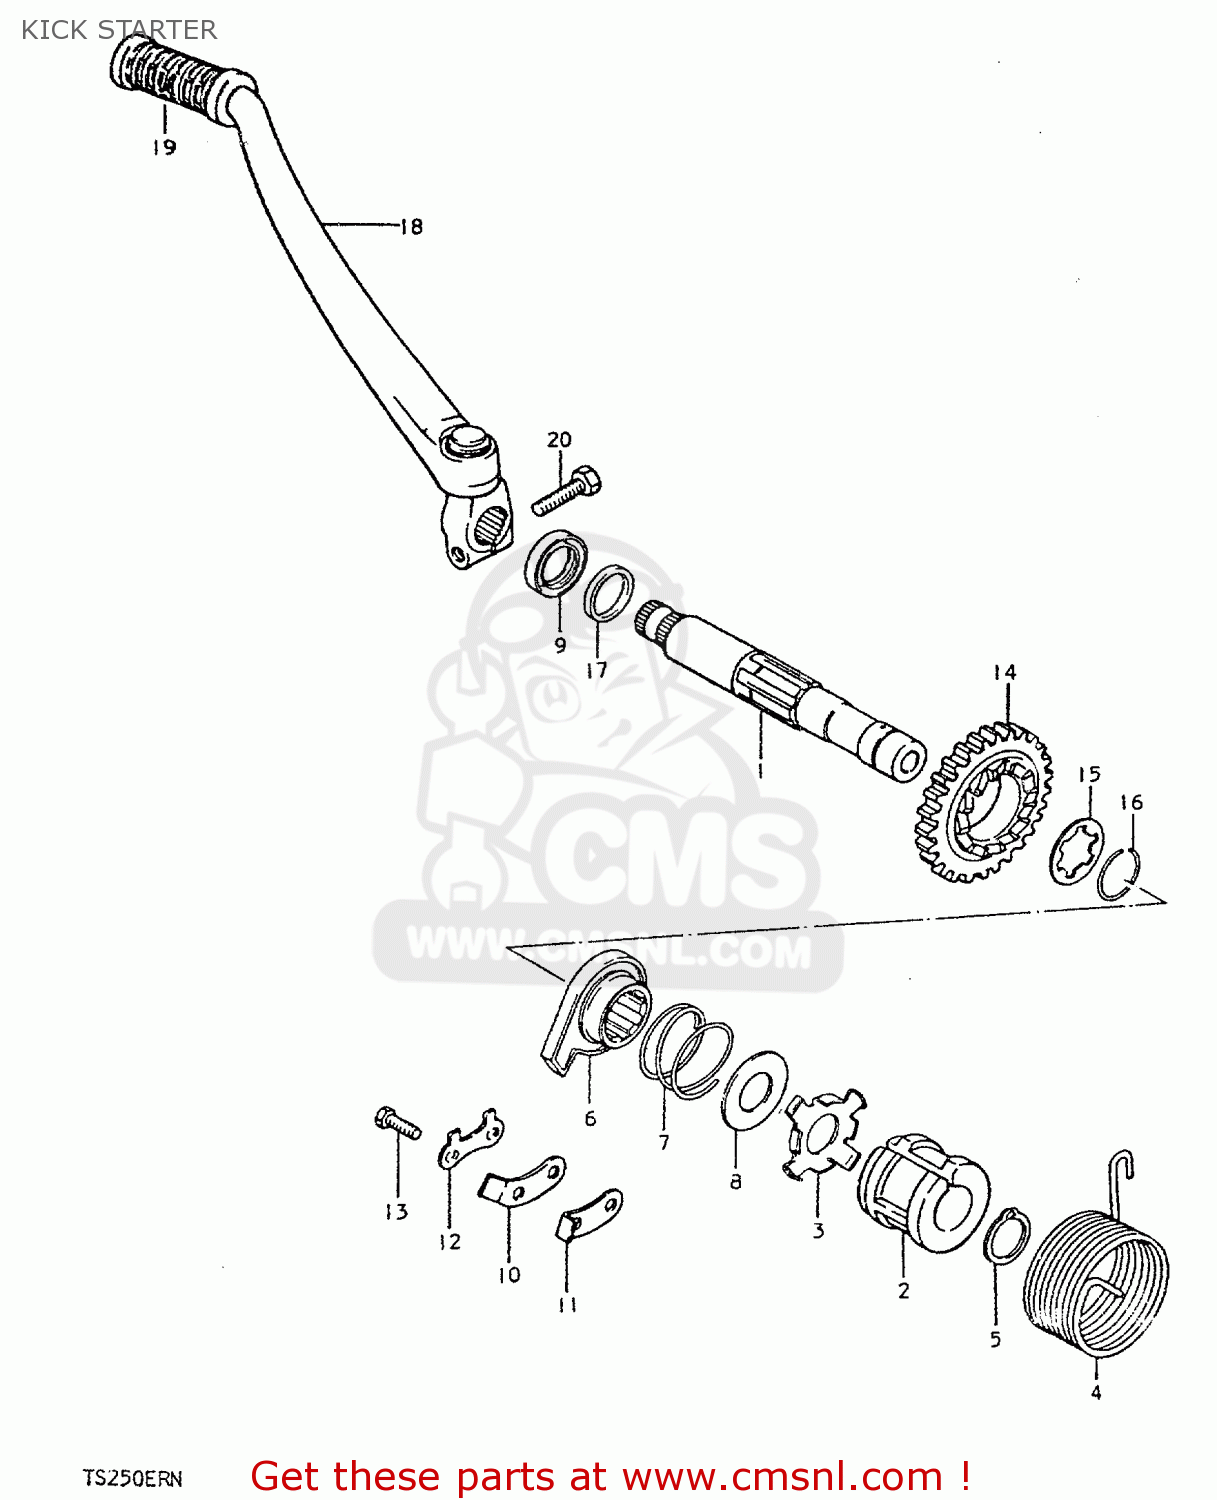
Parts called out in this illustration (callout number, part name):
1	SHAFT,KICK STARTER
2	GUIDE,KICK SHAFT SPRING
3	HOLDER,KICK SHAFT SPRING
4	SPRING
5	CIRCLIP
6	STARTER,KICK
7	SPRING
8	WASHER
9	SEAL,OIL(20X37X7)
10	GUIDE,KICK STARTER
11	STOPPER,KICK STARTER
12	WASHER
13	BOLT, UPPER
14	GEAR,KICK STARTER DRIVE
15	WASHER,LOCK
16	CIRCLIP
17	SPACER(20X28X4.5)
18	LEVER ASSEMBLY,KICK STARTER
19	RUBBER,KICK STARTER PEDAL
20	BOLT
